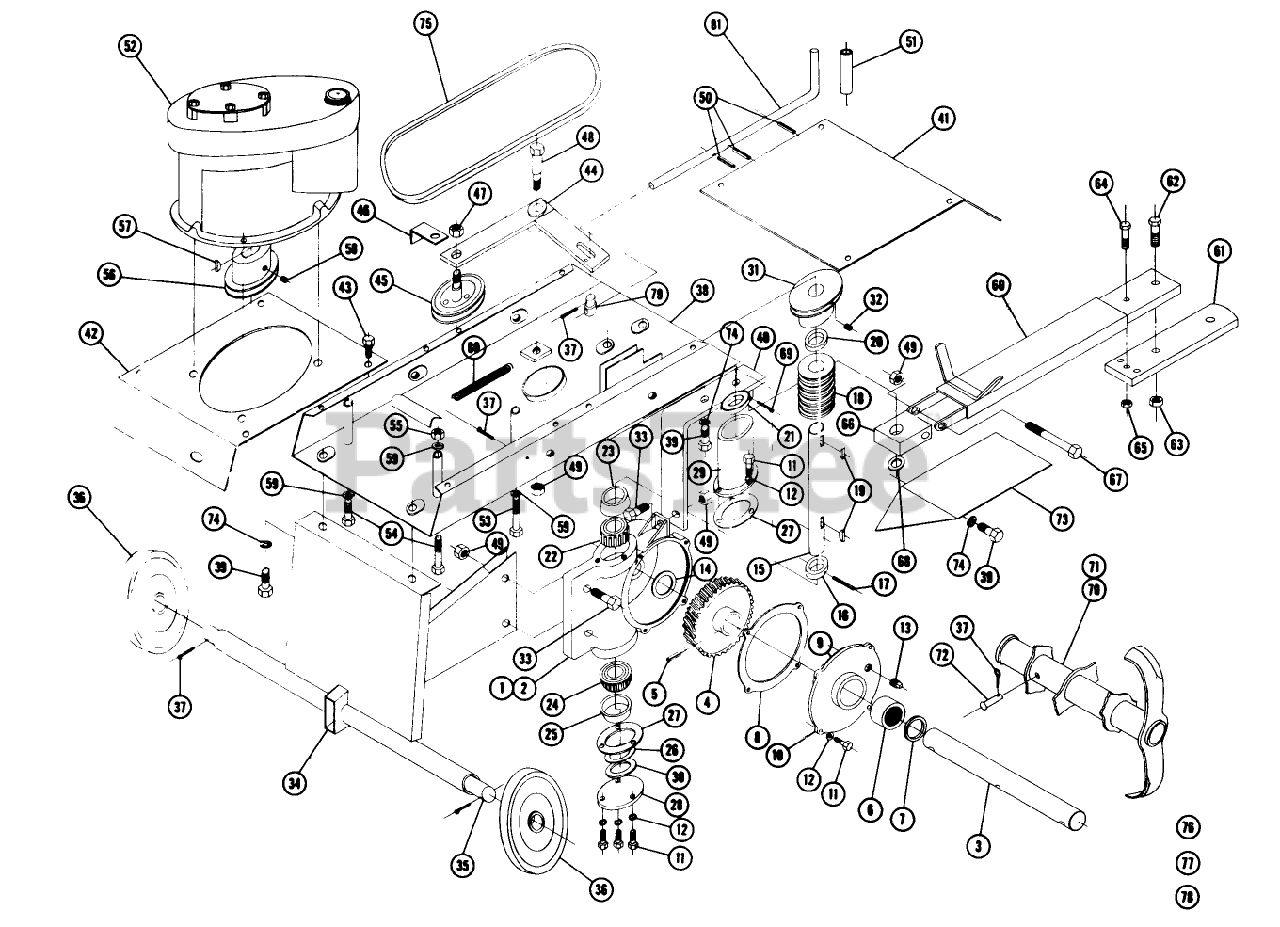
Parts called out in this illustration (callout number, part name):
1	Ass-y. Worm Gear Box
2	Case
3	Shaft-Tine
4	Gear-Worm
5	SPIROL PIN
8	Gasket
9	Shim
10	Cover
11	Bolt-1/4-20 x 5/8
12	Washer
13	Pipe Plug 1/8-27
14	Shim
15	Shaft-Worm
17	PIN-ROLL
18	Worm
19	Key
20	Spacer
22	Cone-Bearing
27	Gasket
28	Plate
29	Support
31	Pulley
32	Set Screw 1/4-20 x 1/4
33	Bolt 3/8-16 x 1
34	Pivot Tube W/A
35	Axle
37	Cotter Pin
38	Deck W/A
39	Bolt 3/8-16 x 1
40	Mounting Bar W/A
41	Top Plate
42	Plate-Top Rear
43	Bolt, 1/4-x 1/2
44	Clutch Arm W/A
47	Nut-Hex Jam 1/2-20
48	Bolt-Shoulder
50	Roll Pin
51	Tube Clutch Rod
52	Ass-y. Engine-Lauson 6 H.P.
53	Bolt-Hex 5/16-18 x 3 3/4
54	Bolt, 5/16-18 x 3
55	Nut 5/16-18 Jam
56	Engine Pulley
57	WOODRUFF KEY
58	Set Screw 5/16-18 x 5/16
59	Lockwasher
60	Ass-y. Hitch Bar
61	Plate-Hitch Bar
62	Bolt Hex 1/2-13 x 1 1/2
63	Locknut-1/2-13
64	Bolt, 3/8-16 x 1/2
65	3/8-16 E.S.
66	Block-Swivel
67	Bolt 3/8-16 x 2 1/2
68	Washer, 5/8
69	Cotter Pin 3/16 x 1
70	Ass-y. Tine Tube R.H.
71	Ass-y. Tine Tube L.H.
73	Cover-Tine
74	Lockwasher
77	Decal-Caution
79	Stud
81	Rod-Clutch
